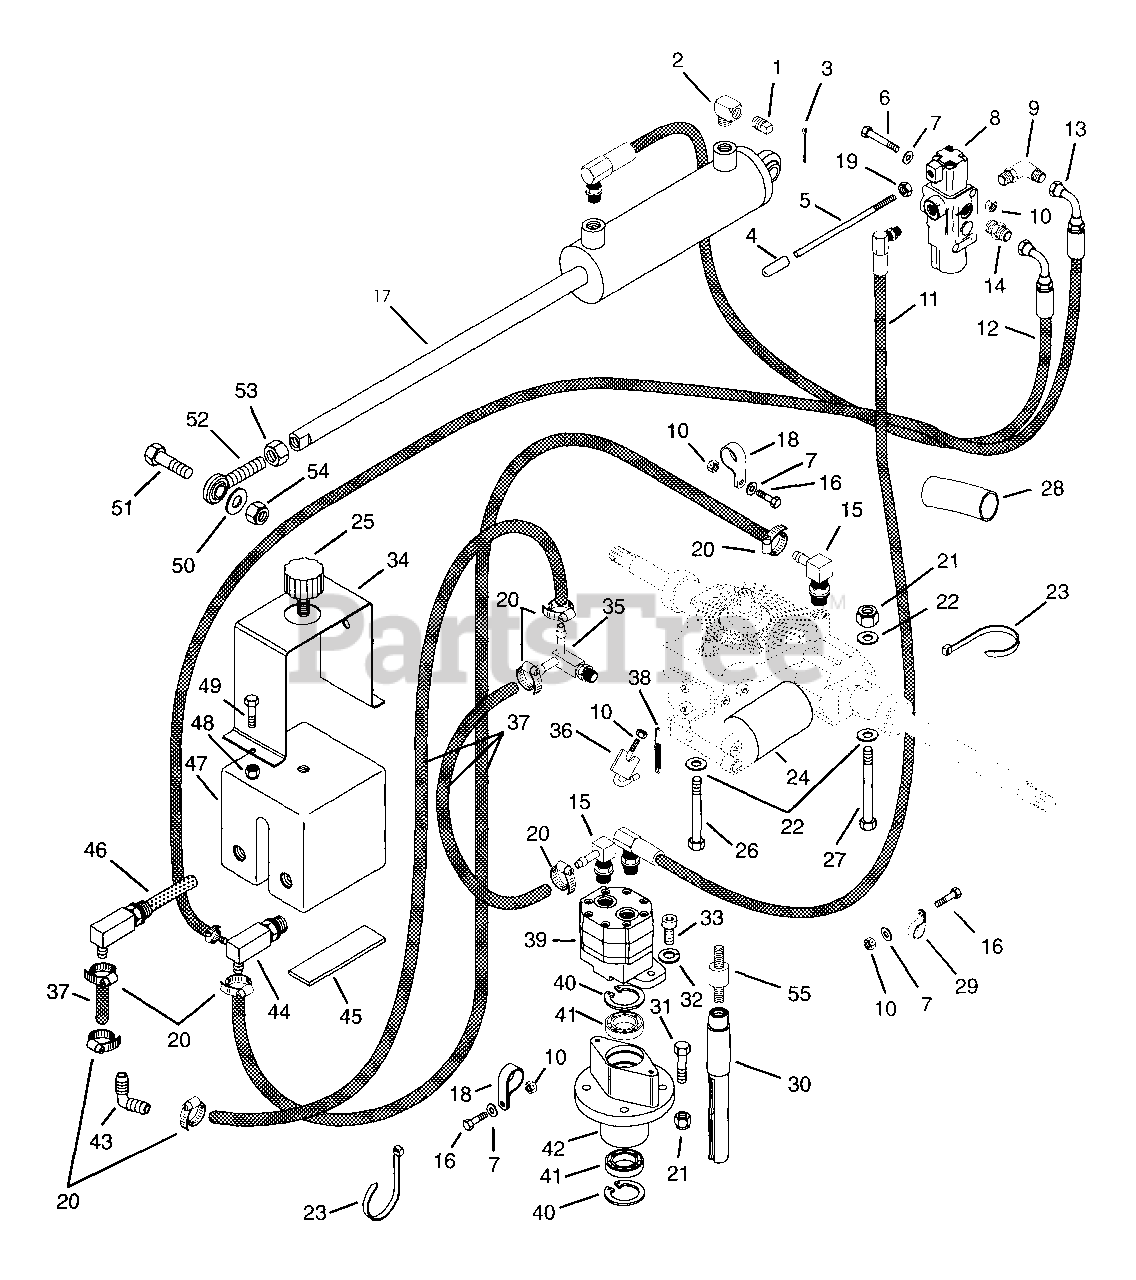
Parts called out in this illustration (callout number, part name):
1	Plug-Breather
2	Adapter 6MB-6FP x 90
3	Pin-Cotter .12 x 1.25
4	Grip-PTO Lever
5	Rod-Hydraulic Lift
6	Bolt-Hex .25-20 x 3.00
7	Washer-Flat-Steel .281 x .62 x .065
8	Valve-Hydraulic
9	Fitting-Adapter (TF5515-6-8)
10	Nut-Locking-Center .25-20
11	Assembly-Hydraulic Hose
12	Assembly-Pressure Hose
13	Assembly-Hydraulic Hose
14	Adapter-Pipe .56-18 "O" Ring to .56-18 M37
15	Fitting
16	Bolt-Hex .25-20 x .75 Grade 5
17	Cylinder
18	Clamp, Steel 1.0
19	Nut-Jam M10-1.5
20	Clamp .88 Dia. Hose
21	Nut-Locking-Center.375-16
22	Washer-Flat-Steel .406 X .812 X .065
23	Tie Wrap-Black
24	Filter-Oil
25	Cap-Filter
26	Bolt-Hex .38-16 x 3.25 Grade 5
27	Bolt-Hex .38-16 x 4.00 Grade 5
28	Sleeve-Protective
29	Clamp-Cushioned Steel
31	Bolt-Hex .38-16 x 1.50 Grade 5
32	Washer-Locking .38 x .094
33	Screw-Cap 38-16 x .75 Socket Head
34	Strap-Tank
35	Fitting-Pipe .875-14
36	Weldment Lever
37	Hose
38	Spring-Tension .061 x .50 x 3.5
39	Pump-Hydraulic
40	Ring-Retaining-Internal 2.210 x .062
41	Bearing-Ball 1.0 x 2.0 x .56
43	Elbow-Barbed .63 x .63
44	Fitting with O-Ring 88-14 x .268
45	Pad, Gas Tank
46	Fitting-Filter
47	Tank Hydraulic
48	Nut-Locking-Center .31-18
49	Bolt-Hex .31-18 x .75 Grade 5
50	Washer-Flat-Steel .50 x 1.25 x .083
51	Bolt-Hex .50-13 x 1.50 Grade 5
52	Assembly-Rod End (Right Hand)
53	Nut-Jam .50-20 Grade 2
54	Nut-Locking-Center .50-13
55	Coupler, Drive
